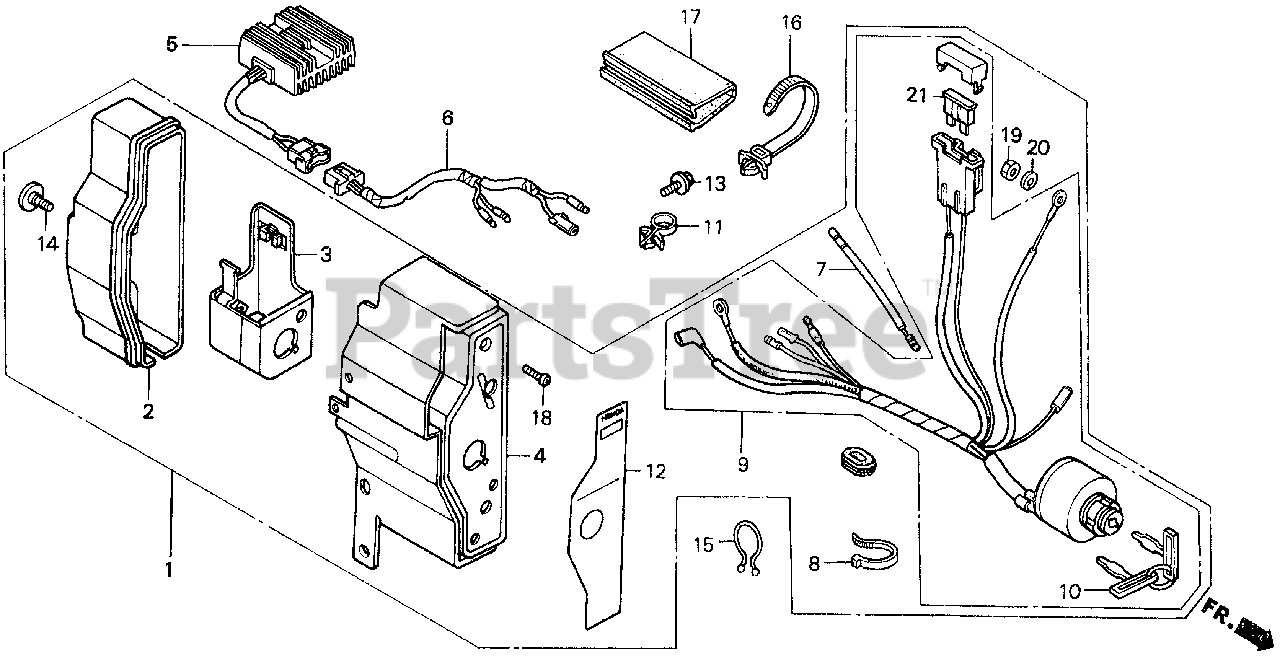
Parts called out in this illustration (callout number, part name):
1	BOX ASSY., CONTROL (EXTERNAL-ALERT-18A) *NH1* (BLACK)
1	BOX ASSY., CONTROL (EXP-ALT,18A) *R8* (BRIGHT RED)
2	CASE, CONTROL
3	BRACKET, CASE MOUNTING
4	PANEL, CONTROL *NH1* (BLACK)
4	PANEL, CONTROL *R8* (BRIGHT RED)
5	RECTIFIER ASSY., REGULATOR (20A)
6	SUB-WIRE HARNESS ASSY.
7	SUB-HARNESS
8	BAND
9	SWITCH ASSY., COMBINATION (18A-CHARGE)
10	KEY
11	HOLDER, STOP SWITCH WIRE
12	MARK, CONTROL BOX (EXTERNAL-REGULATOR)
13	BOLT, FLANGE (6X12) (CT200)
14	SCREW, SPECIAL (6X12)
15	CLIP, PURSE LOCK
16	STRAP, CABLE (118MM) *NH1L* (BLACK)
17	TUBE, FASTENER (30)
18	SCREW, PAN (4X12)
19	NUT, HEX. (4MM)
20	WASHER, SPRING (4MM)
21	FUSE, BLADE (25A)
22	ALERT UNIT, OIL
23	WASHER, PLAIN (4MM)
